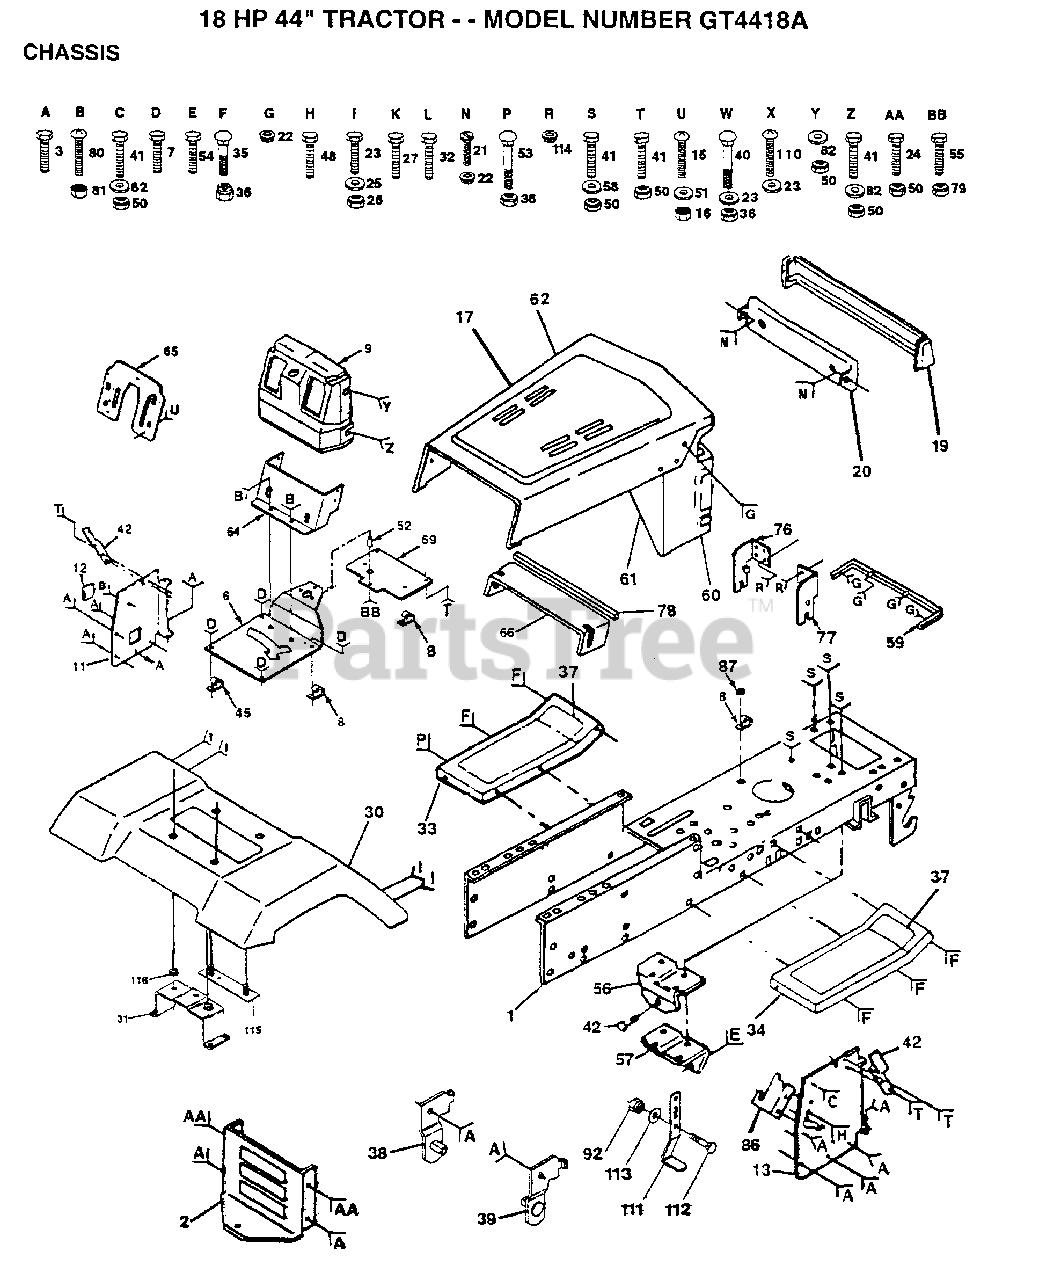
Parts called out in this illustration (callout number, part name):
2	DRAW BAR
3	SCREW
7	SCREW GTV
8	CLIP T
11	PANEL.DASH.LH
12	COVER ACCESS
13	PANEL.DASH.RH
15	SCREW
16	NUT
17	HOOD/GRILLE ASM
21	SCREW SPECIAL
22	PAL NUT LT
23	BOLT
25	WASHER
27	SCREW LT
30	FENDER PNT
31	BRACKET FENDER
32	SCREW
35	BOLT
36	NUT
37	FOOTREST PAD
38	BRACKET ASM LH
39	BRACKET ASM RH
41	BOLT
42	BRACKET.ASM.SUPT.
45	"CLIP,INSULATOR"
48	SCREW
50	NUT
51	WASHER PM
52	SPACER
54	SCREW LT
55	BOLT
56	SUPPORT-SADDL T
57	SUPPORT.SADDLE.FT
58	LOCKWASHER
59	STRAP FENDER ASM
60	GRILLE ASM WELD
61	PANEL SIDE RH ASM
62	PANEL SIDE LH ASM
64	DASH-LOWER YT
65	PLATE DASH SILKSC
66	"BAFFLE,HOOD"
69	PLATE.SUPT.BATTER
76	BRACKET.RH
77	BRACKET.LH
78	FOAM STRIP T
79	NUT
80	SCREW
82	WASHER
92	NUT
111	STOP.OVER.CENTER
112	BOLT
113	WASHER GT
114	PAL NUT
115	STRAP ASM FENDER
116	NUT-PUSH YT
